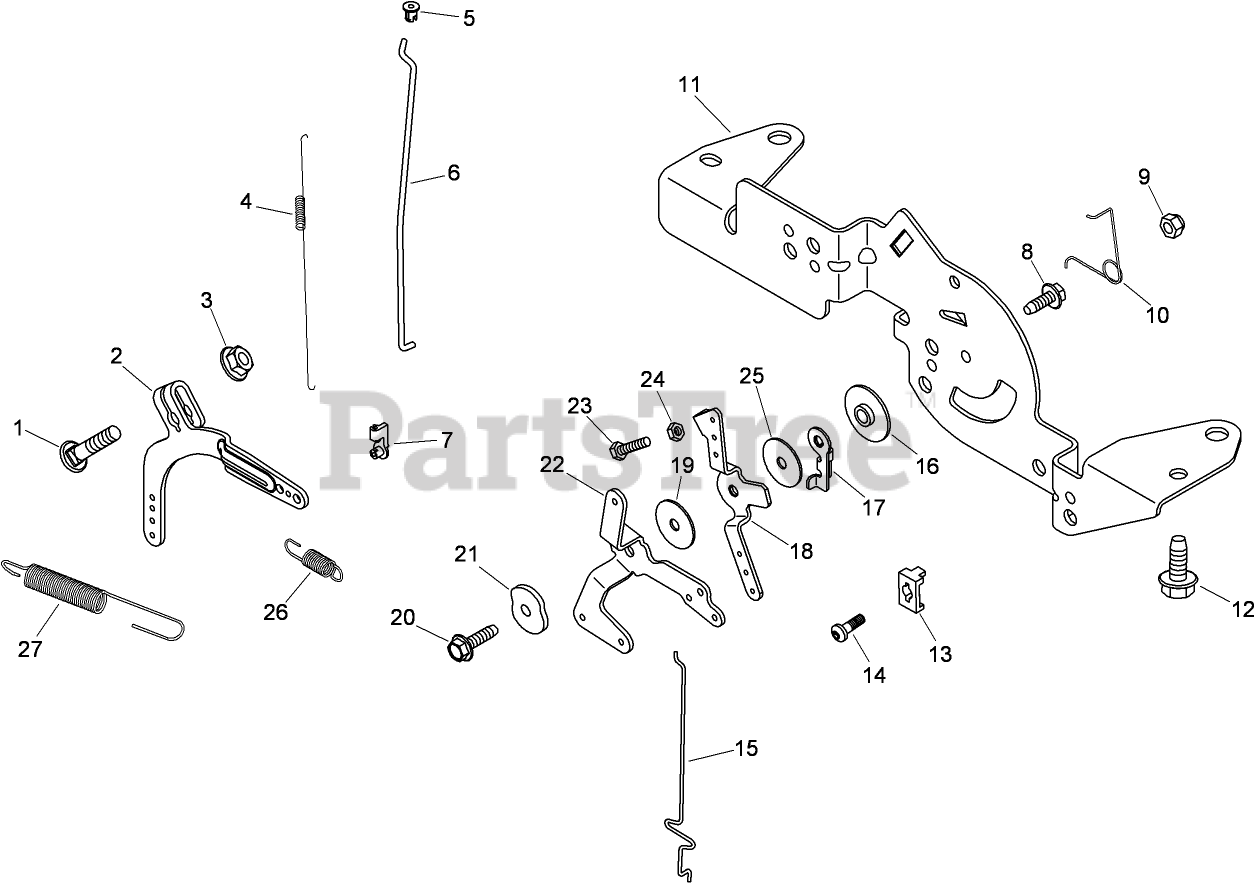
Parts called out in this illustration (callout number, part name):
1	BOLT-SQ NECK, RD HD (M6X1.0X25)
2	LEVER-GOVERNOR
3	NUT-FLANGE (M6X1.0)
4	SPRING-LINKAGE
5	BUSHING-LINKAGE, THROTTLE
6	LINKAGE-THROTTLE
7	BUSHING-RETAINING, LINKAGE
8	SCREW-FLANGE, THREAD FORMING (M5X0.8X16)
9	NUT-LOCK (M5X.8)
10	SPRING-RETURN, CHOKE
11	BRACKET-CONTROL
12	SCREW-FLANGE, THREAD FORMING (M6X1.0X16)
13	CLAMP-CABLE
14	SCREW-LBD, THD FRM (M5X0.8X16)
15	LINKAGE-CHOKE
16	CONTROL SPACER ASM
17	LEVER-ACTUATOR, THROTTLE
18	LEVER-CONTROL, THROTTLE
19	WASHER-FLAT (5.5MM)
20	SCREW-FLANGE, THREAD FORMING (M5X.8X20)
21	WASHER-SPRING (1/4)
22	LEVER-CHOKE
23	SCREW-SLOTTED HEAD (M4X0.7X25)
24	NUT (M4X0.7)
25	WASHER-FLAT (5MM)
26	SPRING-GOVERNOR
27	SPRING-GOVERNOR
